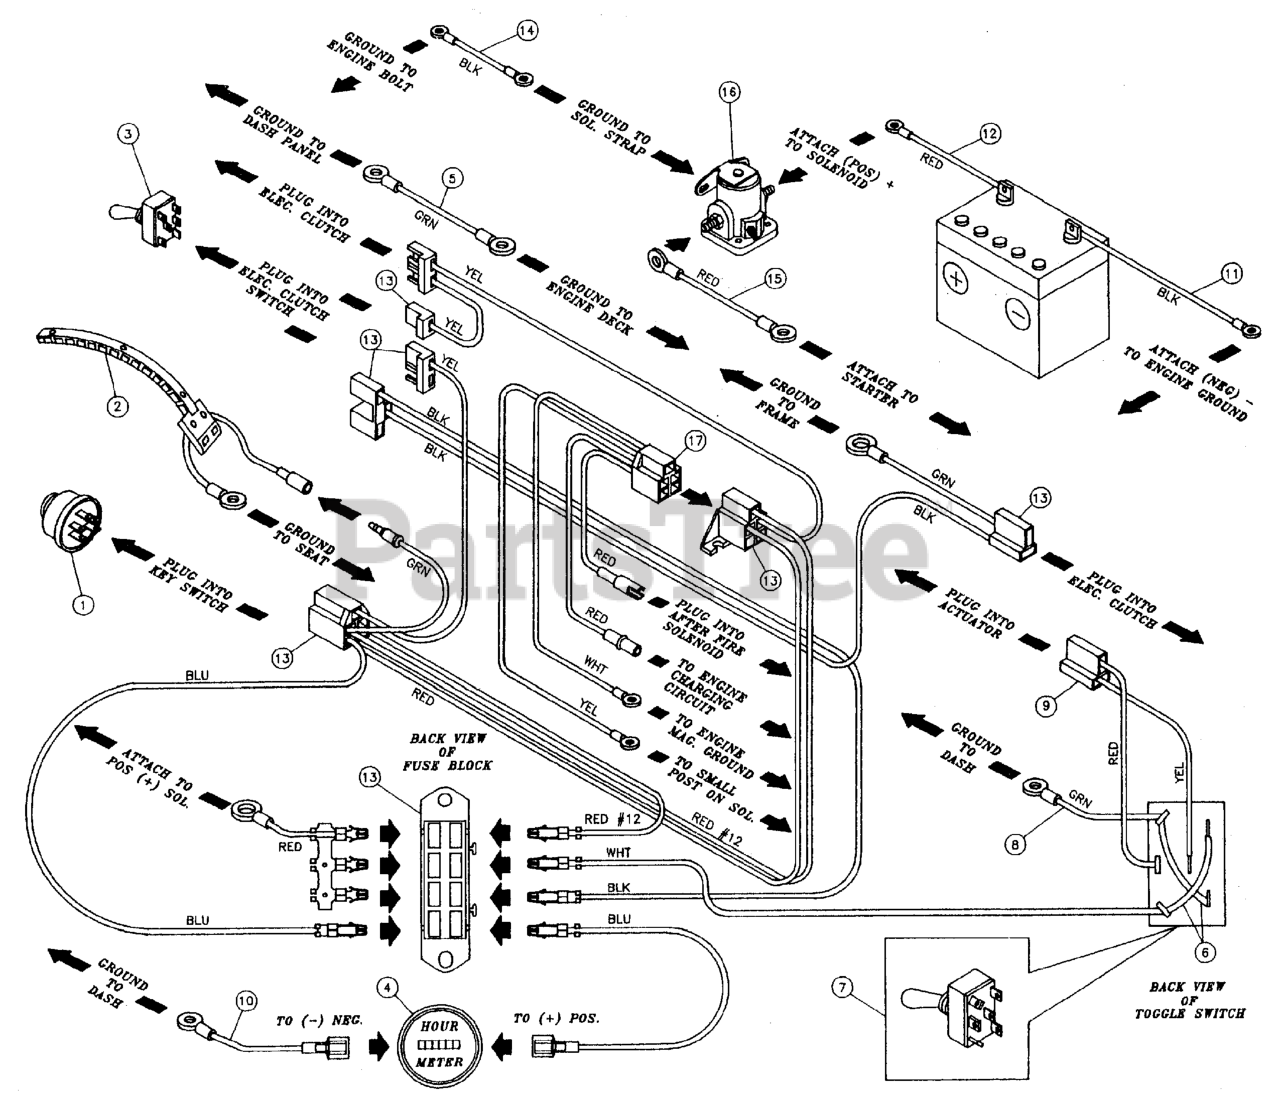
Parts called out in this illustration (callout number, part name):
1	SWITCH, IGNITION, 6 POST
2	Seat Switch
3	SWITCH, Electric Clutch
4	HOUR METER
5	Dash Ground Wire
6	Jumper Wire
7	Actuator Switch
8	Switch Ground Wire
9	Actuator Wire Assembly
10	Hour Meter Ground Wire
11	BATTERY CABLE, NEG, 22, 1/4-5/16
12	POSITIVE (+) BATTERY CABLE, 30"
13	Rider Main Harness
14	CABLE, Ground
15	STARTER CABLE
16	SOLENOID, Starter
17	Briggs Adapter Harness
